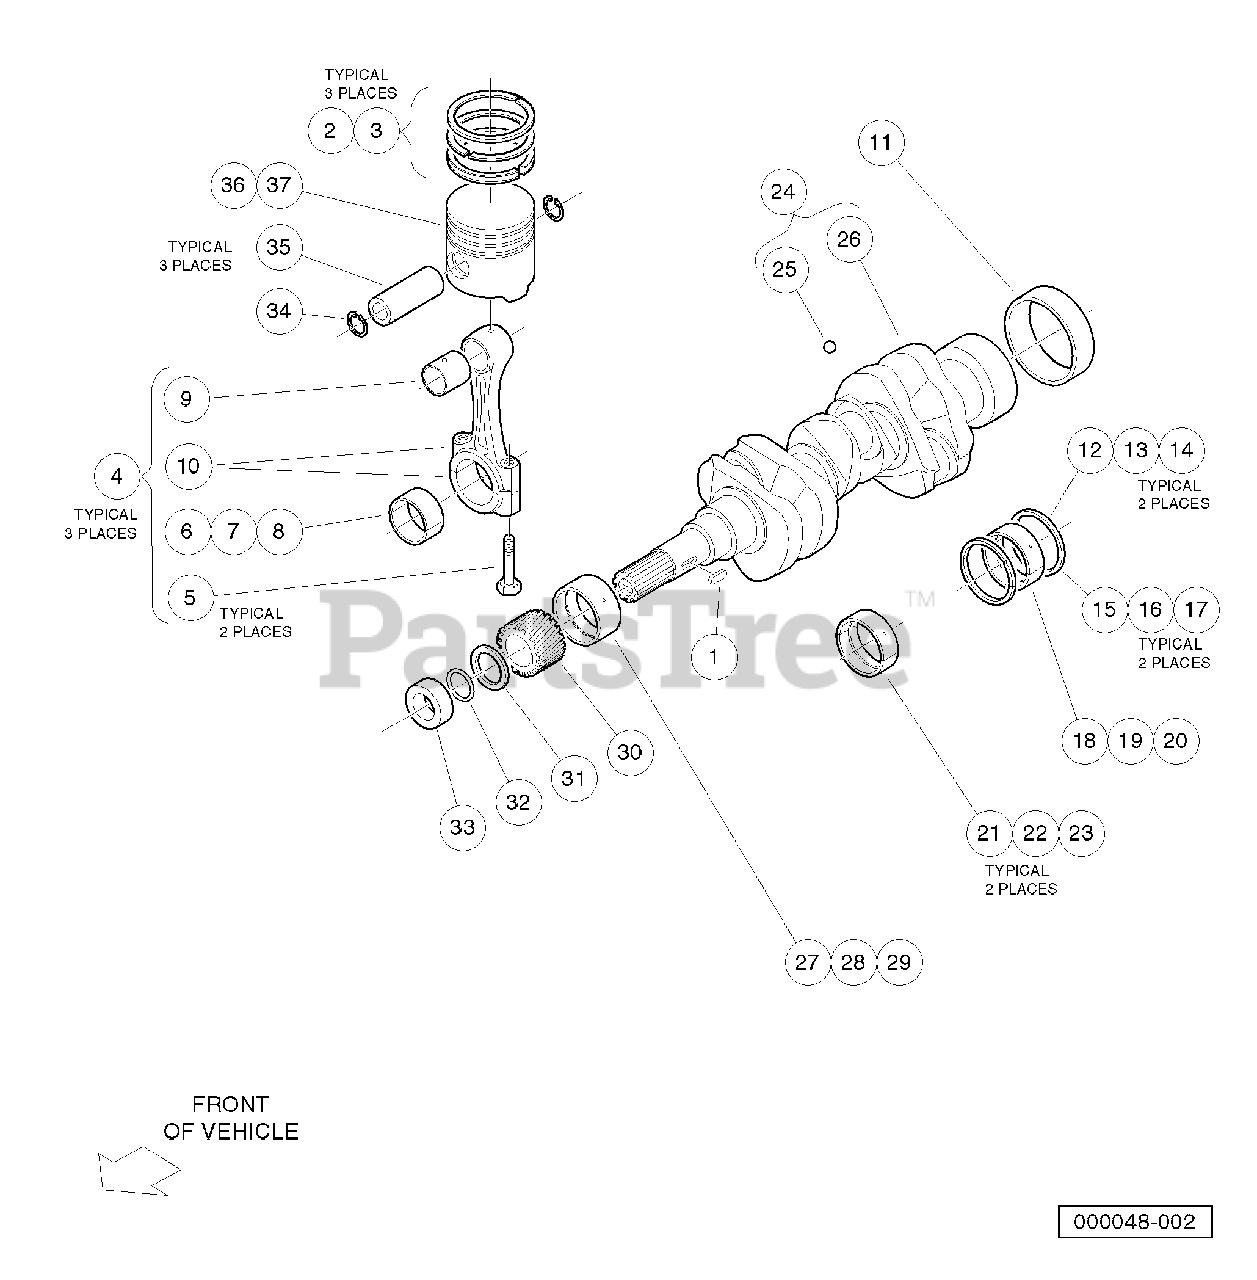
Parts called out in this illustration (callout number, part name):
1	Key, Feather, Short Camshaft
2	Assy Piston Ring, D722 Std
3	Assy Piston Ring, D722 +.025
4	Assy, Connecting Rod
5	Bolt, Connecting Rod
6	Metal, Crank, Rod, D722, Std
7	Metal, Crank, Rod, D722, .020
8	Metal, Crank, Rod, D722, .040
9	Bushing, Piston Pin, D722
10	Rod, Connecting
11	Sleeve, Crankshaft
12	Metal,crank, O Side, Std
13	Metal,crank, O Side, +.020
14	Metal,crank, O Side, +.040
15	Metal,crank, I Side, Std
16	Metal,crank, I Side, +.020
17	Metal,crank, I Side, +.040
18	Metal, Crank, Main, Rear Std
19	Metal, Crank, Main, Rear -.020
20	Metal, Crank, Main, Rear -.040
21	Metal, Crank, Main, Mid Std
22	Metal, Crank, Main, Mid +.020
23	Metal, Crank, Main, Mid +.040
24	Crankshaft
25	Ball, Crankshaft
26	Crankshaft
27	Metal, Crank, D722, Frnt, Std
28	Metal, Crank, 722, Frnt, -.020
29	Metal, Crank, 722, Frnt, -.040
30	Gear, Crank
31	Slinger, Oil
32	O Ring, 23 X 26
33	Collar, Crankshaft
34	Circlip, Piston Pin
35	Pin, Piston
36	Piston, D722, Std
37	Piston, D722, +0.25
